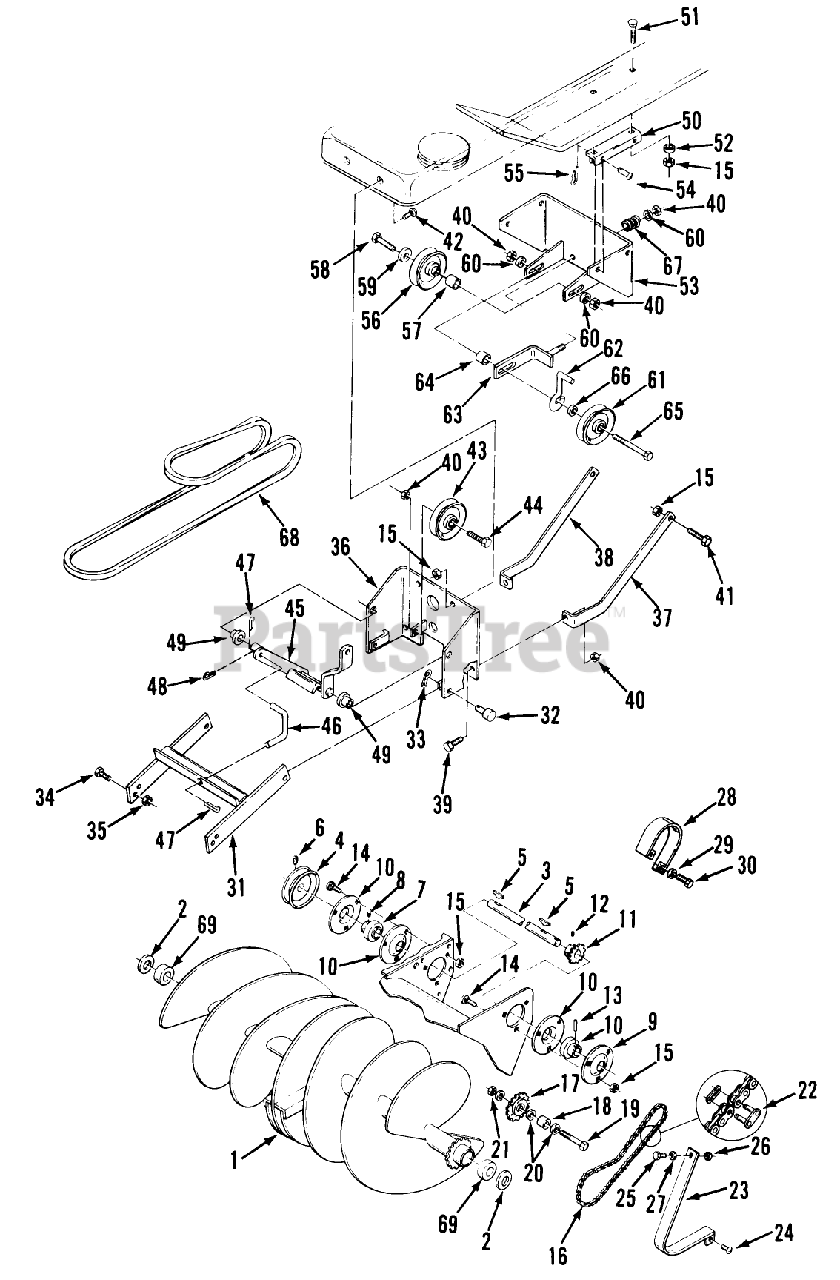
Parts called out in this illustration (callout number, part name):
1	Auger
2	Washer
3	Drive Shaft
4	Pulley
5	Key
6	Set Screw
7	BALL BEARING
8	SET SCREW
9	LUTCO BALL BEARING
10	FLANGE
11	SPROCKET 12T R
12	SCREW-SET
13	PIN-ROLL, SPIROL
14	Bolt
15	Nut
16	Chain-1/2 Pitch #40-62 Pitches
17	Idler Sprocket
18	SPACER
19	Bolt 1/2-13 X 2
20	Washer
21	Eslok Nut
22	MASTER LINK CHAIN
23	Guard-Outer
24	SCREW
25	H H C S
26	Nut 1/4-20
27	WASHER
28	GUARD-CHAIN R
30	Bolt
31	Mounting Frame
33	Hairpin Cotter
34	BOLT
35	NUT
36	Front Support
37	BRACE-FRAME MT LH R
38	BRACE-FRAME MT RH R
39	BOLT
40	Nut
41	Bolt
42	Bolt-Carriage
43	Flat Idler
44	Bolt
45	ASSY BELLCRANK LI R
46	Frame Lift Rod
47	Pop Rivet
48	Hairpin
49	BUSHING
50	Quick Attach Plate
51	Bolt
52	WASHER 5/16 SAE
53	Idler Support Bracket
55	Hairpin
56	Pulley-V
57	Spacer
58	Bolt
59	Washer
60	WASHER
61	Idler Pulley
62	RETAINER BELT R
63	ASSY IDLER SLIDE R
64	SPACER
65	Bolt
66	Washer
67	SPRING-COMPRESSION
68	Drive Belt (127)
69	BEARING-BALL
